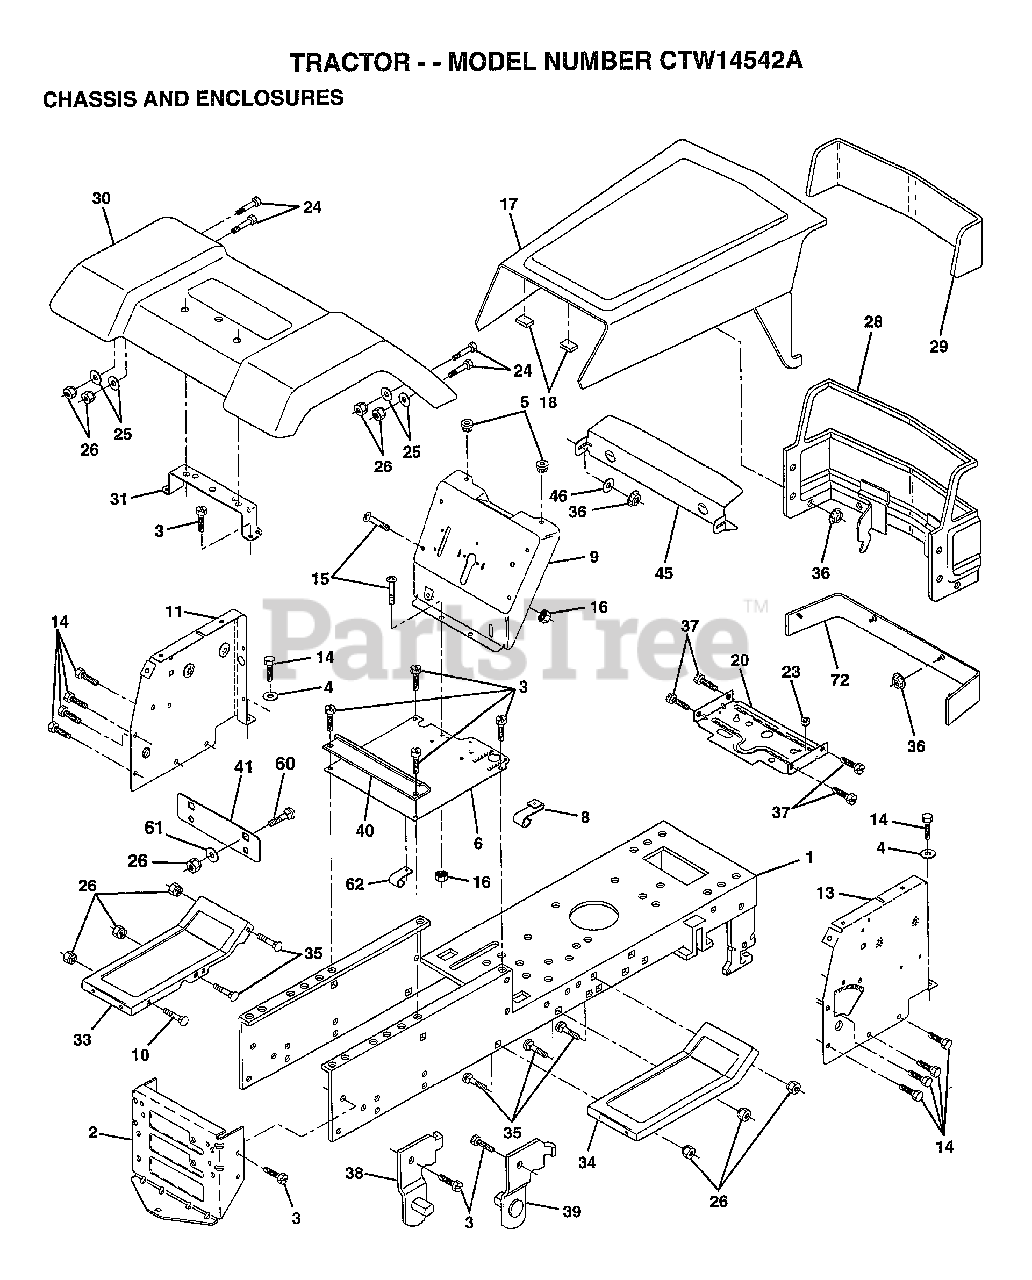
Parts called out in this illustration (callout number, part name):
1	CHASSIS.WLD.11GA
3	SCREW
4	WASHER
6	SADDLE.SLKSCR.6SP
8	"CLIP,INSULATOR"
9	DASH.SLKSC.LT.1PC
11	PANEL.DASH.LH.
14	SCREW LT
15	SCREW
17	HOOD.W/SD.PNLS.LT
20	PLATE.MTG.BTRY.TK
24	BOLT
25	WASHER
26	NUT
31	BRACKET SUPT FEND
33	FOOTREST.LH.PERF.
34	FOOTREST.RH.PERF.
35	BOLT
36	PAL NUT LT
37	SCREW LT
38	BRACKET ASM LH
39	BRACKET ASM RH
40	SPACER FENDER LT
41	PLATE EXTEN FEND
46	RETAINER
60	BOLT
61	WASHER
72	STRAP.GRILLE.PNT.
